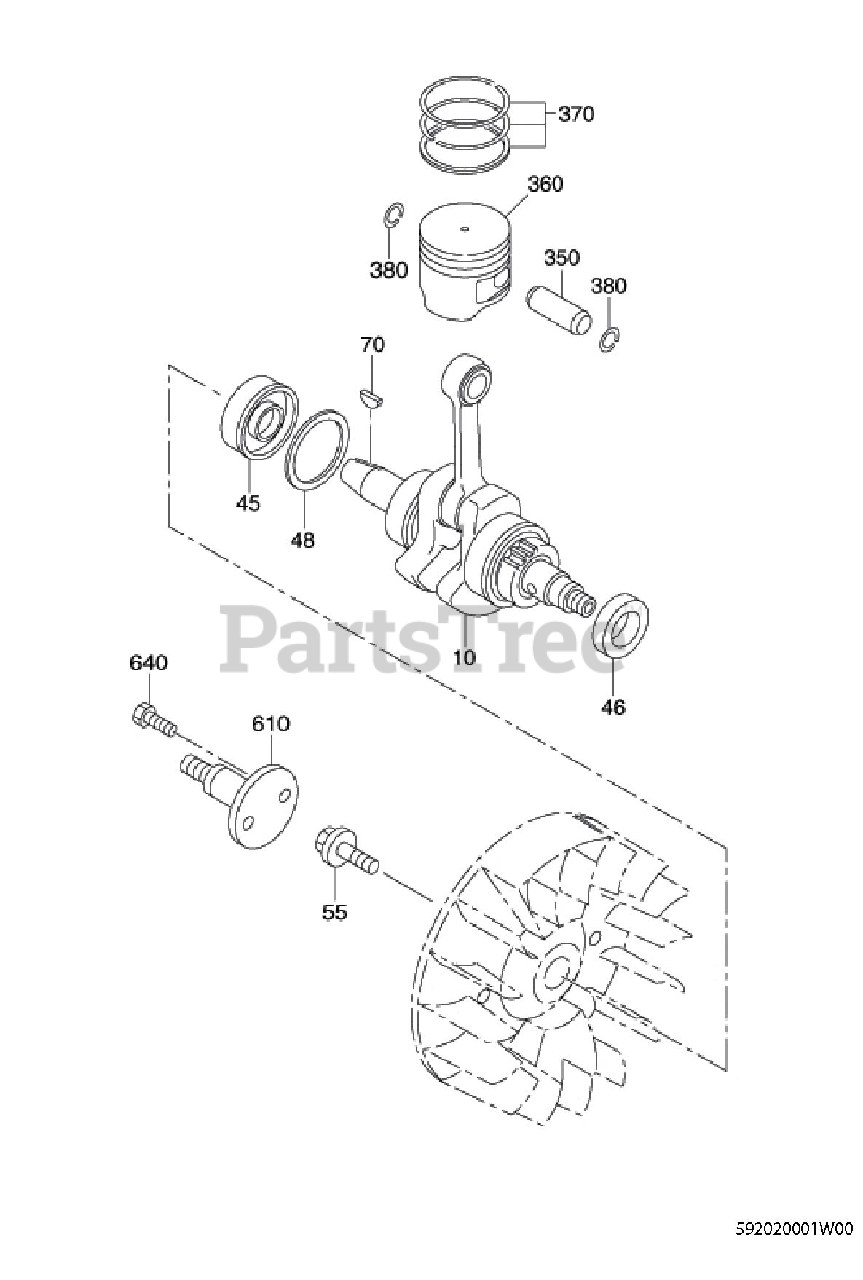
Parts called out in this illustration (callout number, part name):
45	OIL SEAL (L)
46	OIL SEAL 10
48	CLIP
55	HEX HEAD BOLT
70	WOODRUFF KEY 3
350	PISTON PIN
370	PISTON RING SET
640	SCREW AND WASHER AY
